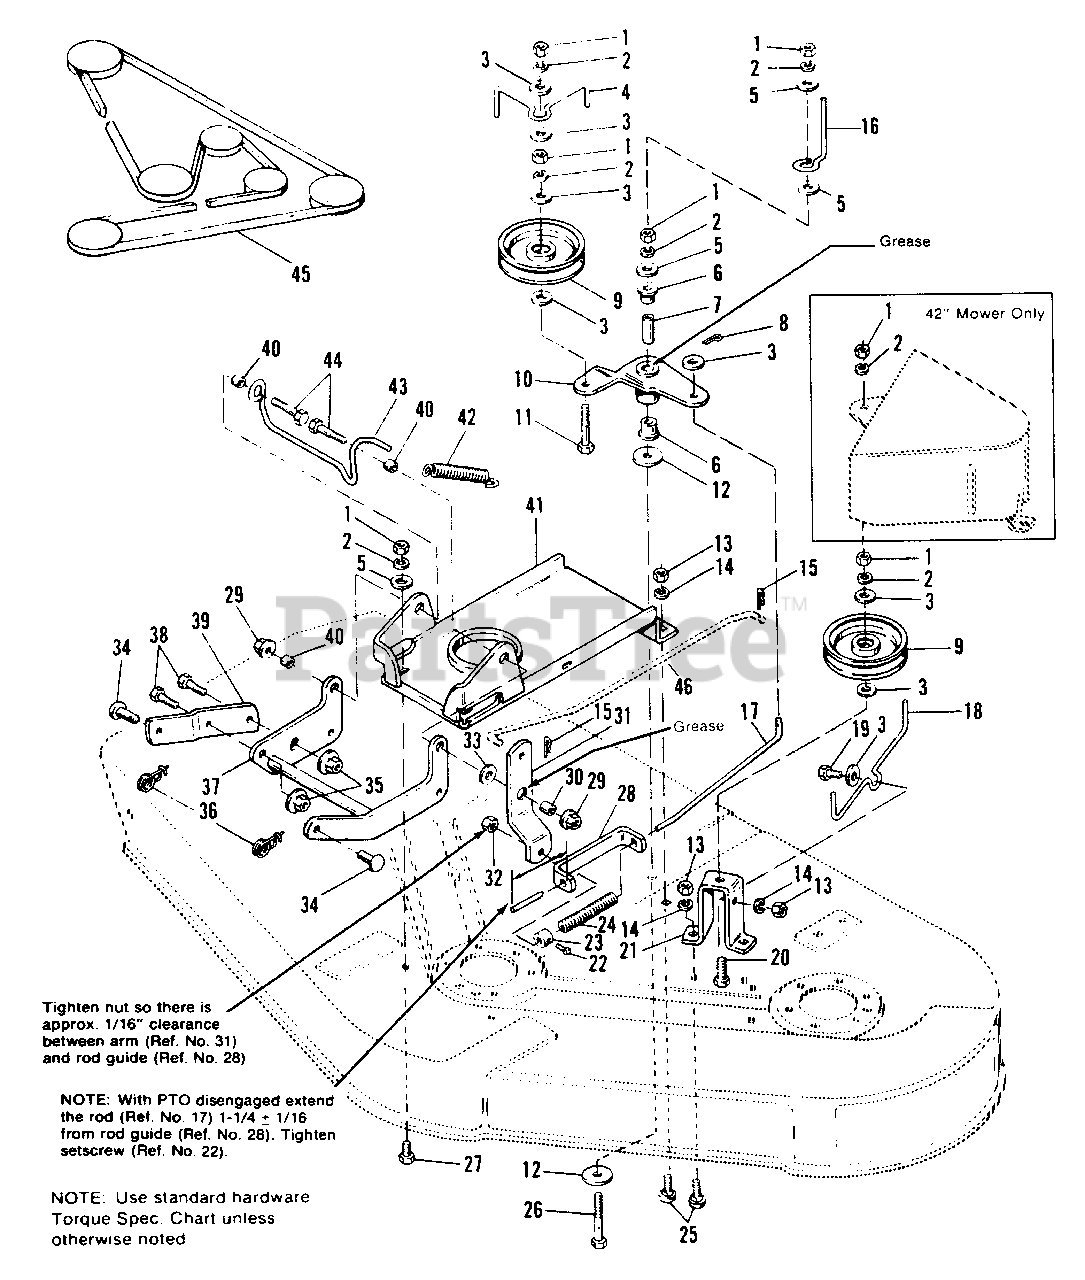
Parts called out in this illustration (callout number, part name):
1	NUT, Hex, 3/8-16 (Qty. 6 on 48" Mower)
2	LOCKWASHER, 3/8 (Qty. 6 on 48" Mower)
3	WASHER, Plain, 5/16
4	STOP, Belt
5	WASHER, Plain, 3/8 (Qty. 3 on 48" Mower)
8	PIN, Cotter, 3/32 x 3/4
9	PULLEY, Idler
10	LEVER ASSY., Clutch
11	CAPSCREW, Hex, 3/8-16 x 2-1/4
12	WASHER, Special
13	NUT, Hex, 5/16-18
14	LOCKWASHER, 5/16
15	PIN, Quick, 1-7/8
16	STOP, Belt (42" Mower)
17	ROD, Clutch, Mower
19	CAPSCREW, Hex, 5/16-18 x 1
20	CAPSCREW, Hex, 3/8-16 x 1-1/4 (48" Mower)
20	CAPSCREW, Hex, 3/8-16 x 2 (42" Mower)
21	SUPPORT, Idler
22	SETSCREW, Sq. Hd., 1/4-20 x 3/8
23	COLLAR, Set
25	BOLT, Carriage, 5/16-18 x 3/4
26	CAPSCREW, Hex, 3/8-16 x 2-3/4 (48" Mower)
26	CAPSCREW, 3/8-16 x 3-1/2 (42" Mower)
27	CAPSCREW, Hex, 3/8-16 x 3/4
28	GUIDE ASSY., Rod
29	NUT, Hex, Flange, 3/8-16
31	ARM, Pivot
32	LOCKNUT, Hex, 5/16-18
33	WASHER, Plain, 5/8
35	LOCKNUT, Flange, Whiz, 3/8-16
36	PIN, Safety
37	ARM ASSY., Rocker
38	CAPSCREW, Hex, 3/8-16 x 1
39	ARM, Rocker
41	SUPPORT ASSY.
42	SPRING, Tension
43	ROD, Brake (48" Mower)
43	ROD, Brake (42" Mower)
44	CAPSCREW, Hex, 3/8-16 x 1-3/4
45	V-BELT, Mower Drive (48" Mower)
45	V-BELT, Mower Drive (42" Mower)
46	ROD, Clutch, Tractor PTO (6116 & 6118)
46	ROD, Clutch, Tractor PTO (6111)
